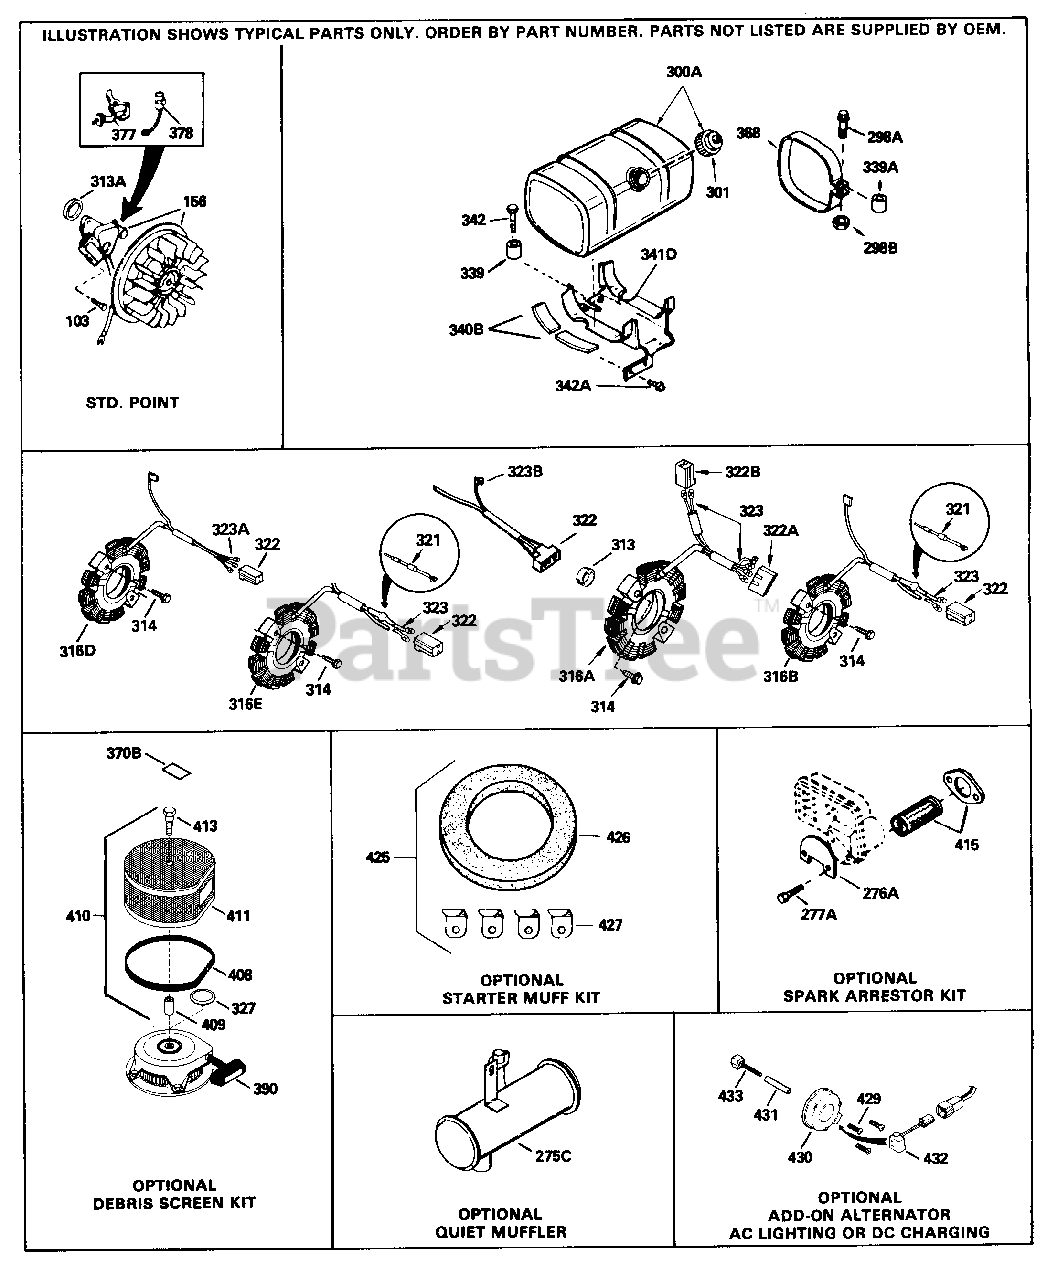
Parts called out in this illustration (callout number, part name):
19	Speed Control Spring
28	Lock Nut, 8-32
242	Air Cleaner Bracket
250	Air Cleaner Cover
264A	Screw, 1/4-20 x 5/8"
307	"O" Ring
327	Starter Plug
342	Screw, T-30, 1/4-20 x 1/2"
390	Rewind Starter Note: This engine cou ld have been built with 590671 starte r. Refer to the design of the air int ake louvers for part identification. individual starter parts do not inter change.
